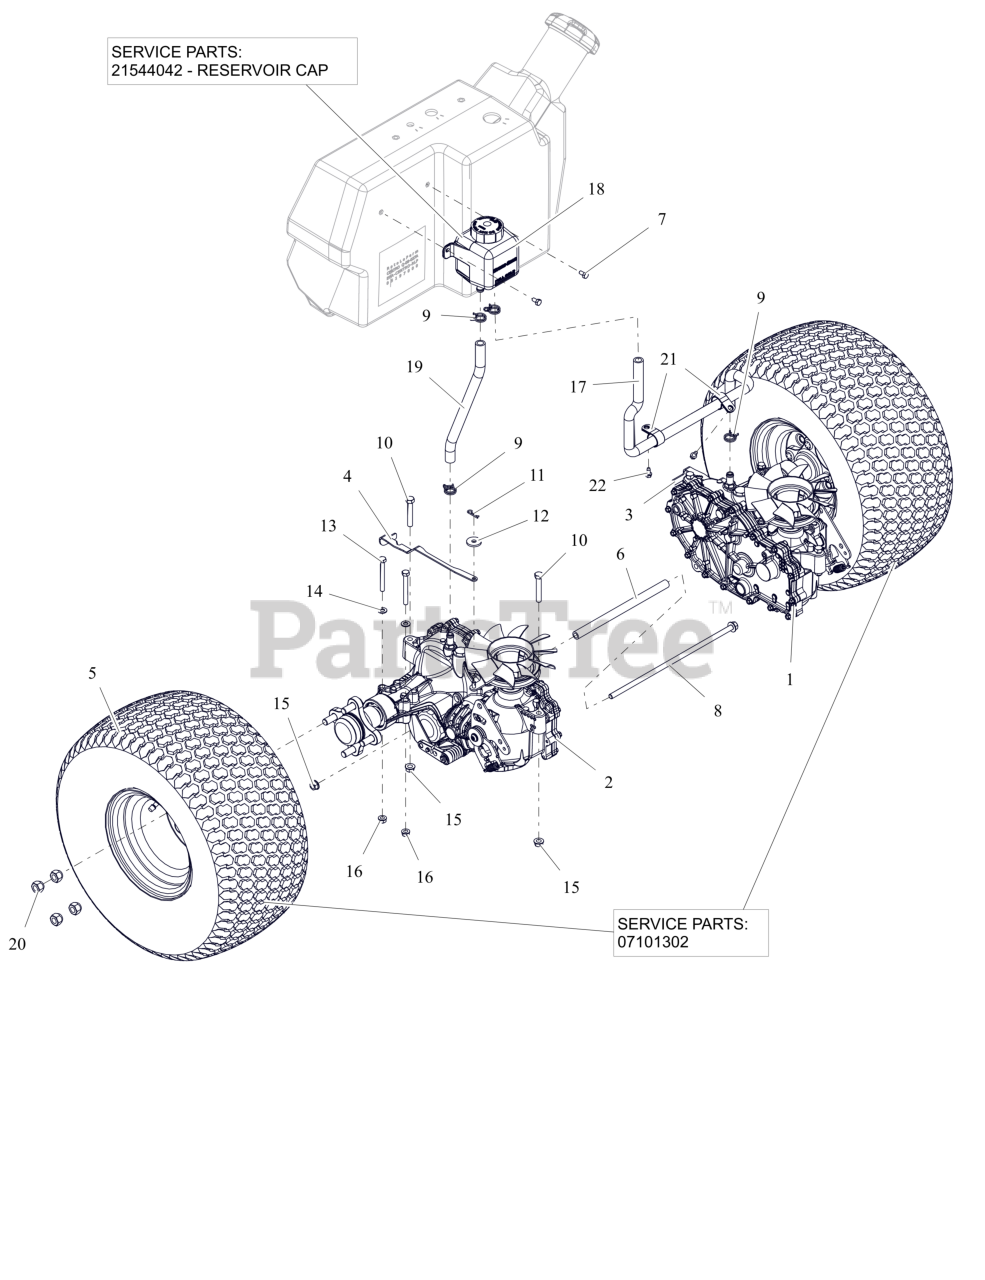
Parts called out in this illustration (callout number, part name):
1	TRANSAXLE- ZT3400 - LH
2	TRANSAXLE- ZT3400 - RH
3	BRKT, HYDRO DUMP - LEFT
4	BRKT, HYDRO DUMP - RIGHT
5	ASSM TIRE/WHEEL 20 X 10.50 - 8
5	TIRE, 20 X 10.5-8 4 PLY RADIAL
6	SPCR,TRANSAXLE
7	BLT,HEX .25-20X.50 G5 ZCC
8	BLT, HEX-FLG 0.375-16X13 GR5 ZC120
9	3/4 WIRE HOSE CLMP ZC
10	BLT,HEX .38-16X2.25 G5 ZCC
11	PIN, HAIR #213 .08X1.19 ZCC
12	WSHR, FLT .340X1.125X.135 ZCC
13	BLT, HEX .31-18X2.75 G5 ZCC
14	WSHR,FLT .344X.688X.065 ZCC
15	NUT-LK-CTR-FLG .375-16 GF ZCC
16	NUT,LK-CTR-FLG .31-18 GF ZCC
17	HOSE, PROSTANCE-OVERFLOW LEFT
18	TANK, HYDRO OVERFLOW 700 ML
18	CAP, HYDRO RESERVOIR REPLAC.
19	HOSE, PROSTANCE-OVERFLOW RIGHT
20	NUT, WHEEL .50-20 ZCC
21	CLAMP, COUSHIONED STEEL REV
22	SCR-TAP .25-20X.50 HWH ZCC
